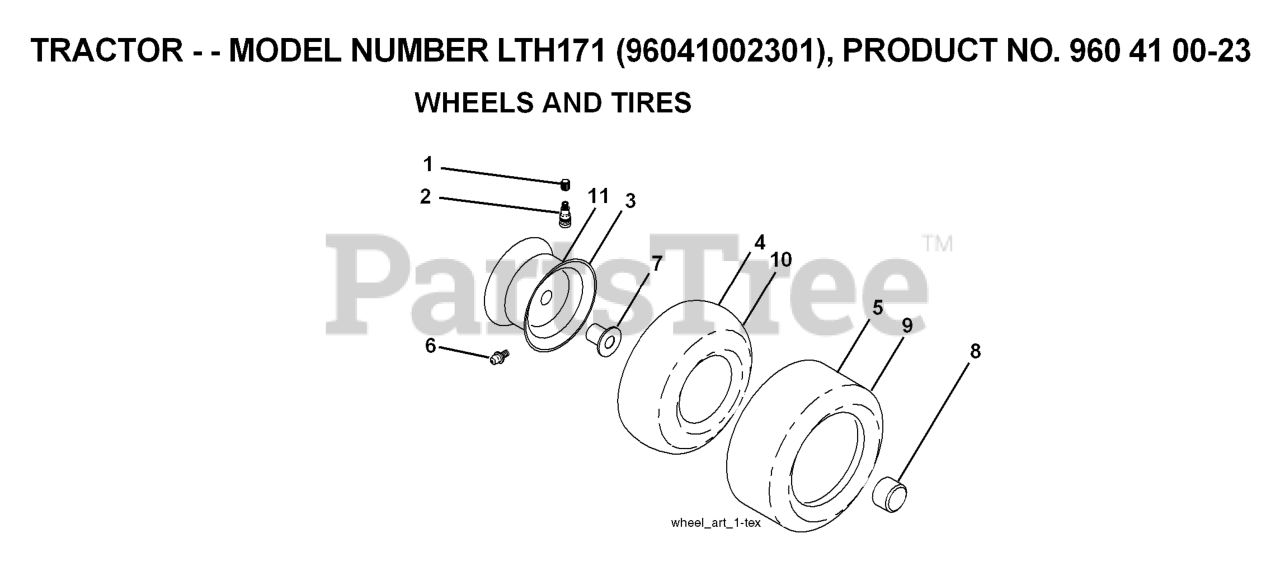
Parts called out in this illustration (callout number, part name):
1	WHEEL, LEFT
2	WHEEL, RIGHT
3	BEARING, WHEEL
4	REAR WHEEL MOUNT, LEFT
5	REAR WHEEL MOUNT, RIGHT
6	SHOULDER BOLT
8	WASHER, 3/8 SPEC
9	WHEEL PLATE, FRONT
10	AXLE WASHER
12	SLW 3/8 STD
13	HCS 3/8-16X1.GRD.5.ZD
14	TIRE, 9" RIGHT
15	TIRE 9" LEFT
